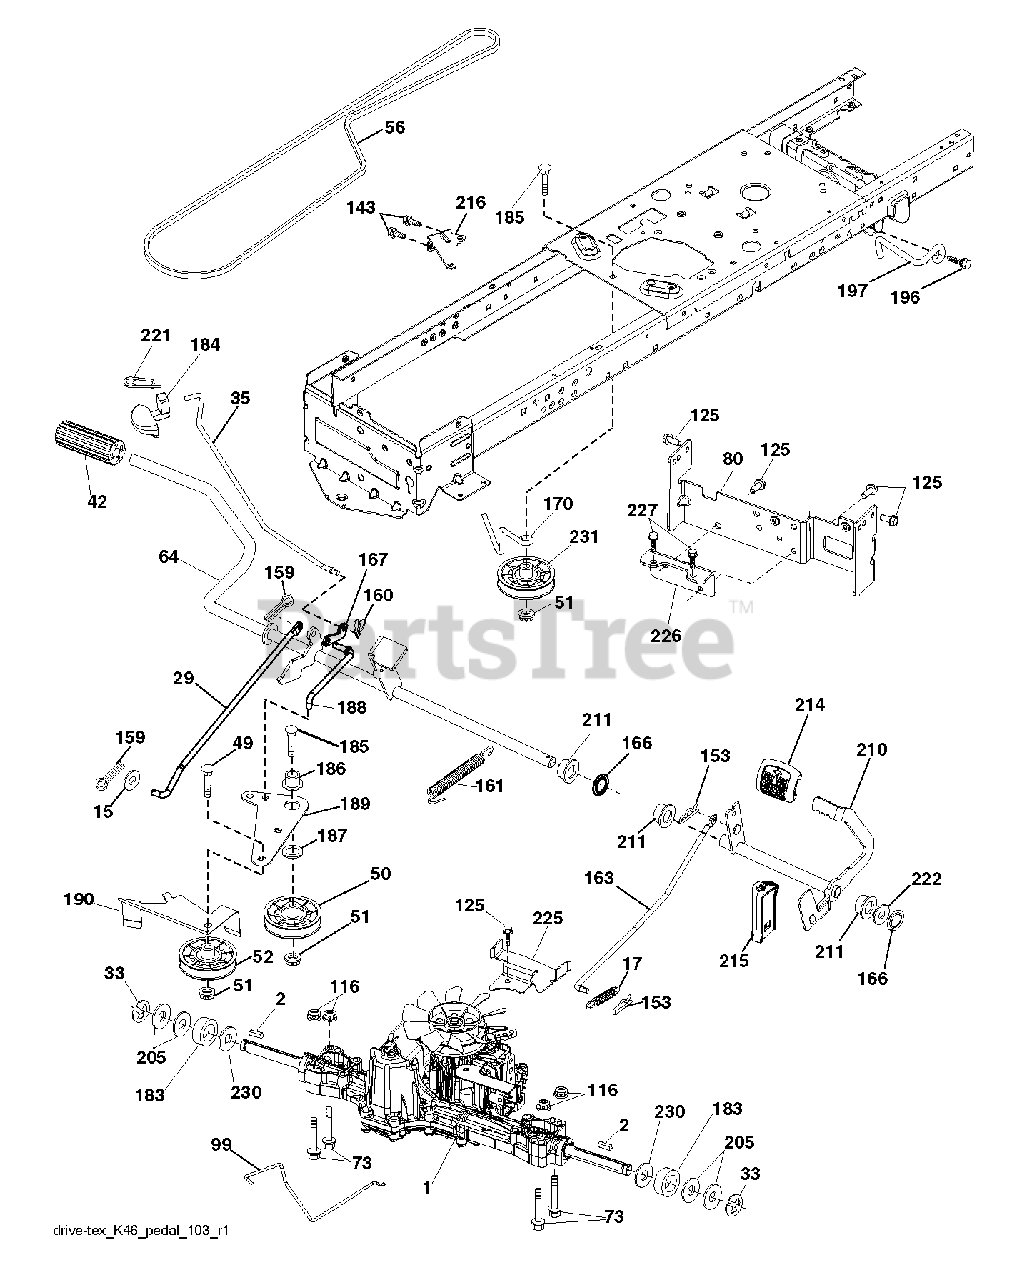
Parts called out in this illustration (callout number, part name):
2	SQUARE KEY
15	WASHER
17	SPRING.BRAKE.K46.GREEN
29	ROD.BRAKE.K46
35	ROD.CNTRL.PARK.PREDATOR.LT.TEX
42	PEDAL COVER T
50	IDLER.FLAT.910.OFFSET
51	NUT LOCK FLG 3/8-16 UNC
52	IDLER.V-GROOVE.910.OFFSET
56	V-BELT.MOWER.92.40.42/K46
64	SHAFT.ASM.PEDAL.BRK.CNTR
80	STRAP.TORQUE.K46.K57R.TT
99	ROD.SPRING.BYPASS.K46.LT.Z
116	NUT LOCK HEX FLANGE 5/16-18
125	SCREW
143	SCREW LT
153	RETAINER M
159	COTTER PIN
160	RETAINER CLIP
161	SPRING, RETURN LT
163	ROD.CONTROL.PEDAL.K46
166	NUT.PUSH.625
167	LATCH.BRAKE.SPRING
170	KEEPER.CENTER SPAN.1.688
183	SPACER AXLE
184	HANDLE.PARKING.BRK.PRED.LT.RED
186	SPACER.RETAINER
187	WASHER 12/32X2X10GA
188	RP LINK.CLUTCH.GROUND.DRIVE
189	BELLCRANK.GROUND.DRIVE.TEX.
190	KEEPER.BELLCRANK.DRIVE
196	SCREW 3/8-16X1
197	LINK.CLUTCH.ANIT-ROTAT
210	ROCKER.ASM.PEDAL.CONTR
211	BEARING.NYLON
214	PEDAL.FORWARD.PAD.TEX
215	PEDAL.REVERSE.TEX.GT.4
216	BRACKET.PULLEY.IDLER.W/TEX
221	RETAINER.SPRING.CLIP.H
222	WASHER 21/32 X 1-1/4 X 10 GA.
225	KEEPER.BELT.TRANSAXLE.K46
226	BRACKET.MOUNT.TORQUE.K46.TLT
227	SCREW
230	WASHER.HARDENED
231	IDLER.V-GROOVE.1.688.OFFSET
